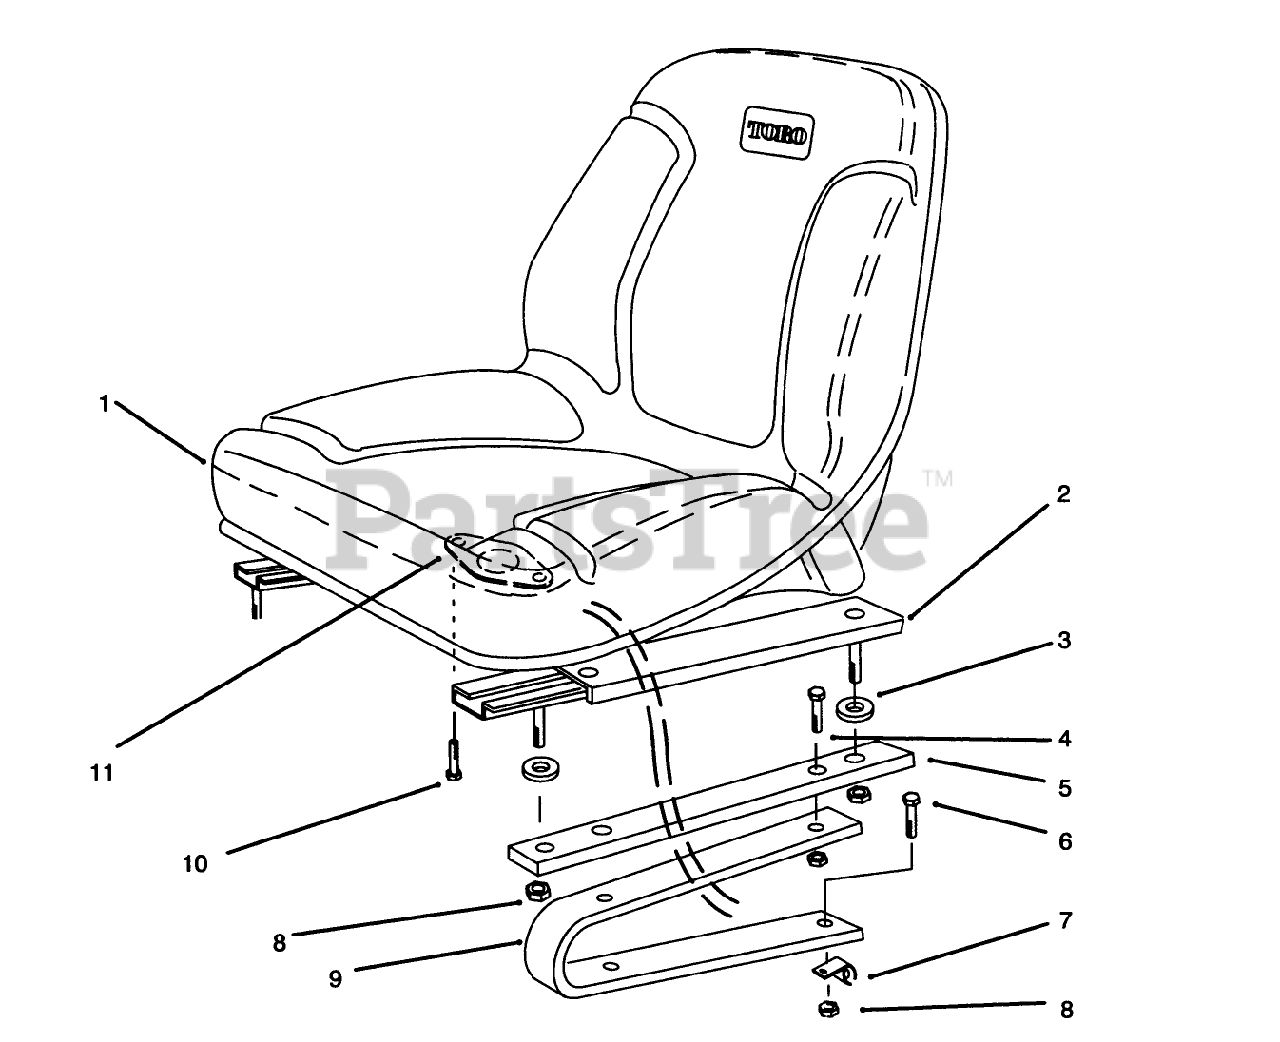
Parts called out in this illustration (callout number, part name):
2	ADJUSTER-SEAT, LH
3	SPACER-NYLON
4	SCREW-HH
6	SCREW-HH
7	CLAMP-R
8	NUT-LOCK, NI
10	SCREW-HH
11	SWITCH-SEAT
